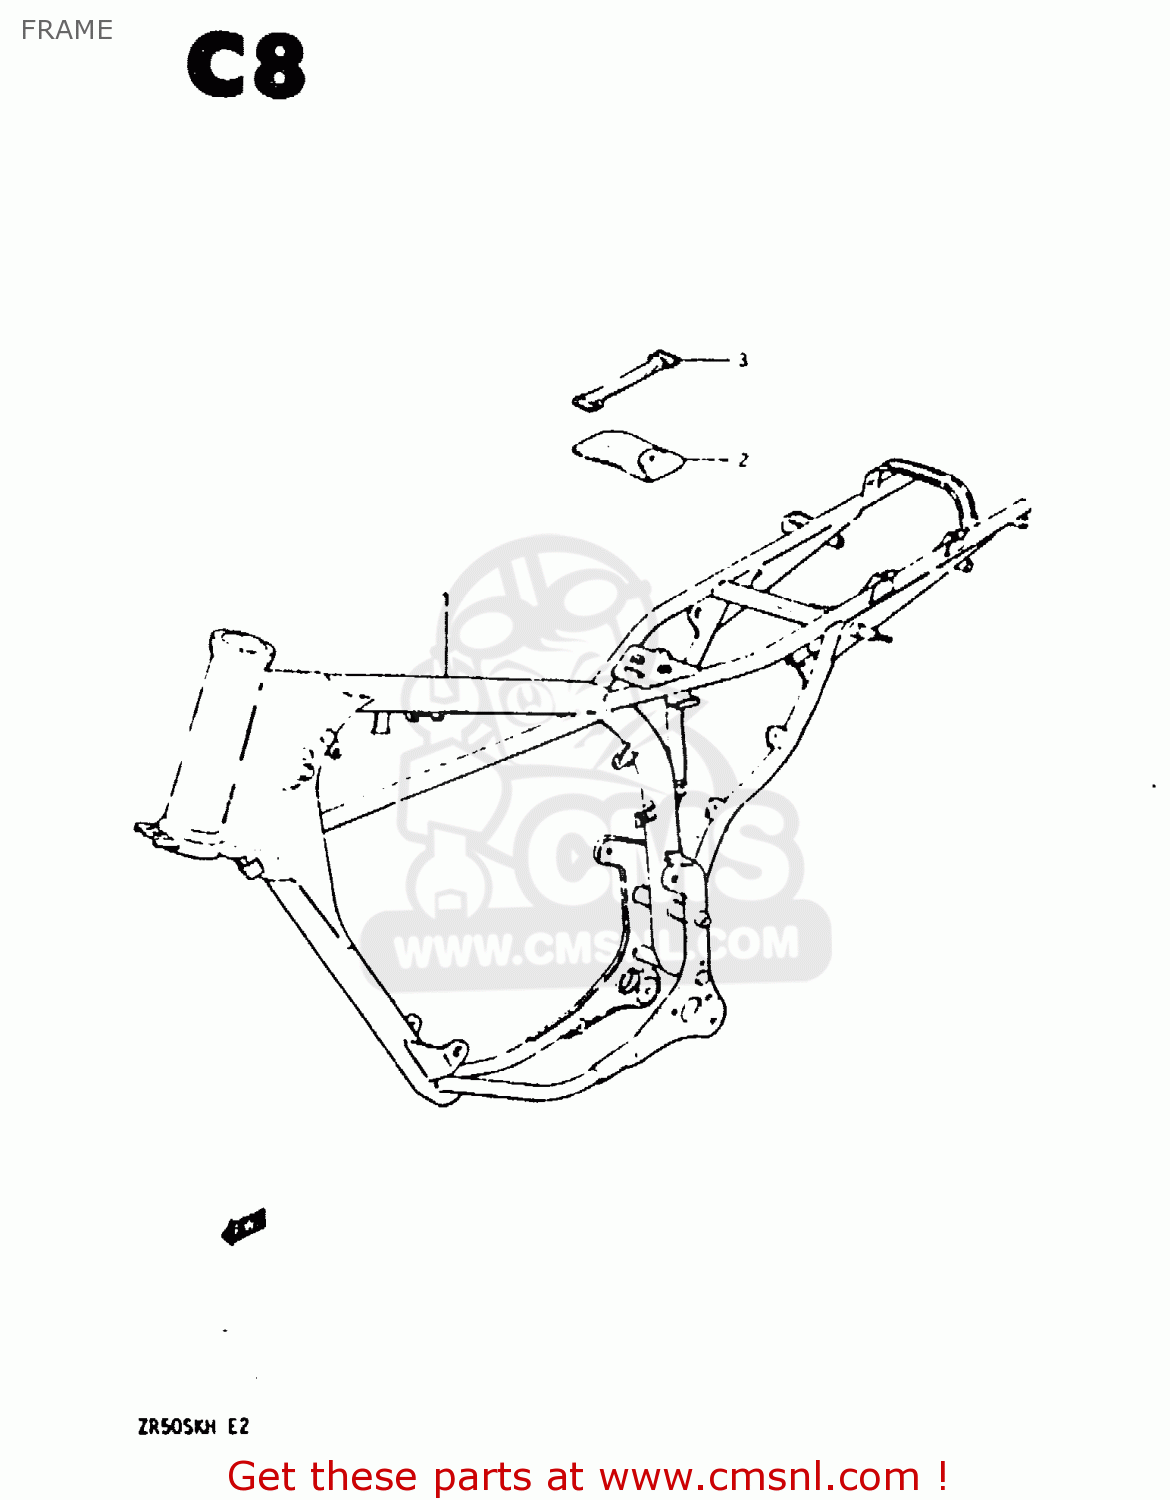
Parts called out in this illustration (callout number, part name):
1	FRAME (BLACK)
2	TOOL SET
3	BAND
